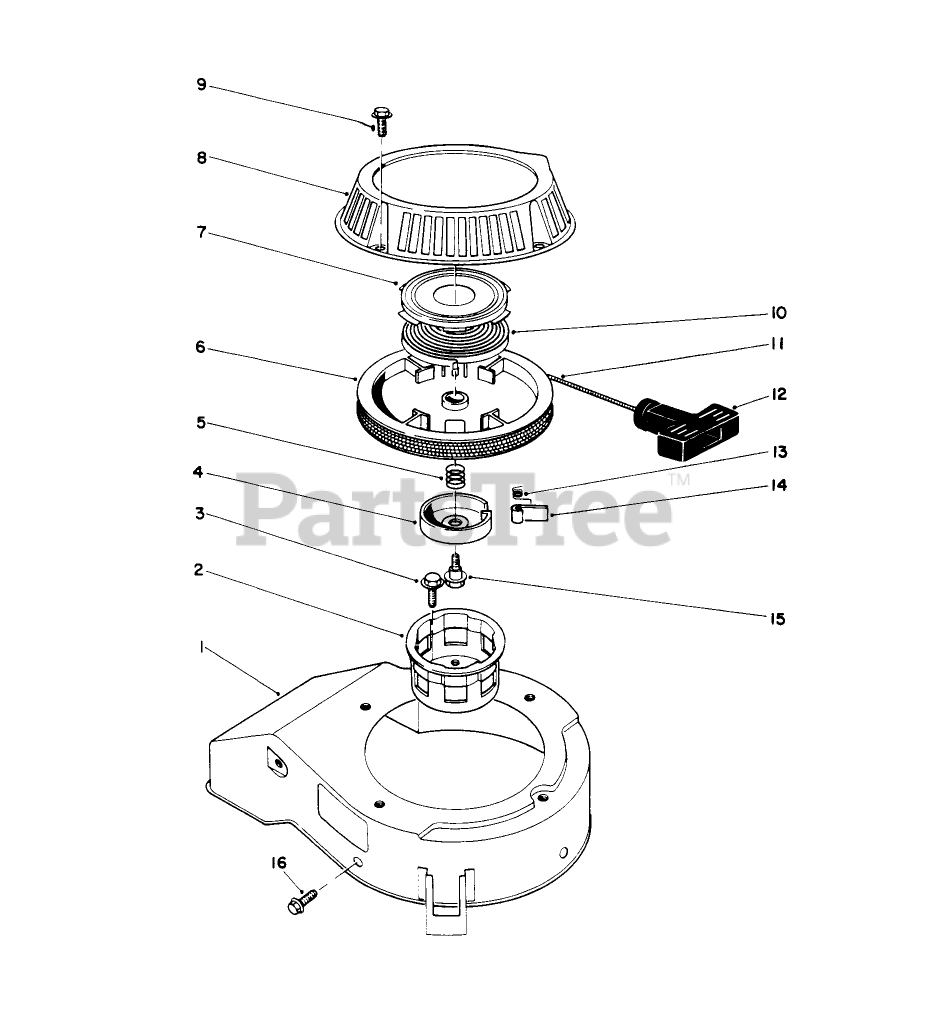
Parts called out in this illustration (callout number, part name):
2	CUP - STARTER
4	RETAINER
5	SPRING
9	SCREW-HHF
12	HANDLE-RECOIL
13	SPRING
